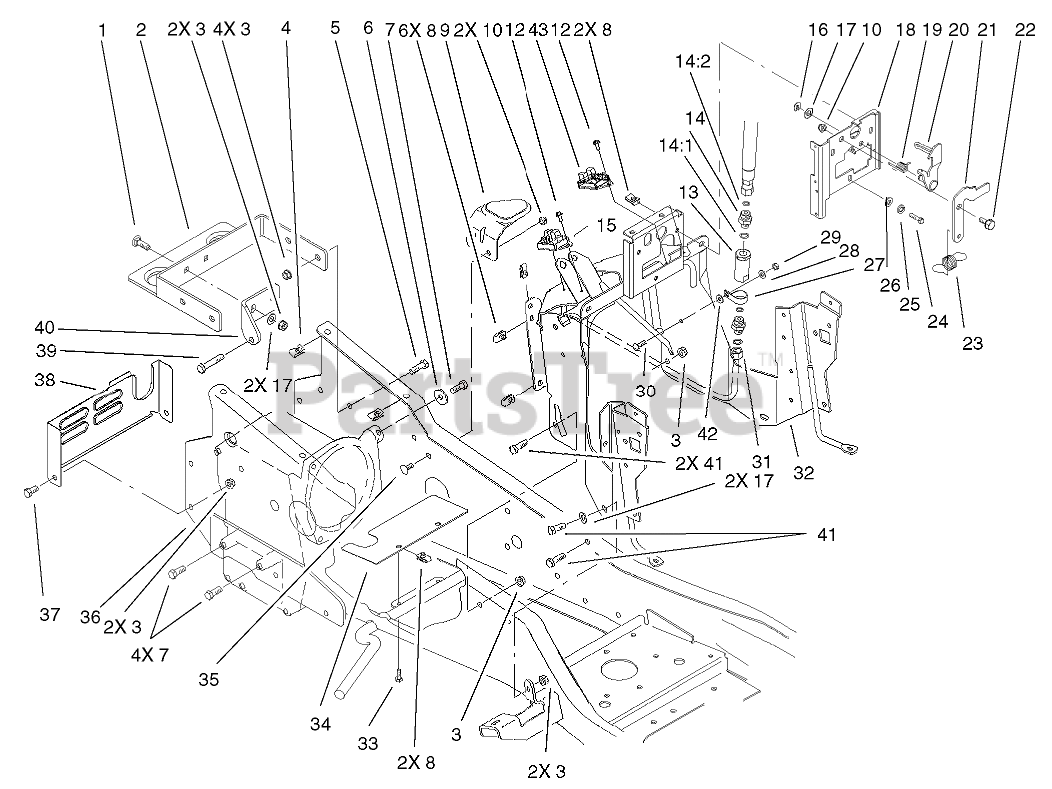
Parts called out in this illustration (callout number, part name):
1	BOLT-CARR
2	Support-Gas Tank
3	NUT-LOCK, NI
4	NUT-U
5	SCREW-HH
6	WASHER
7	SCREW-HH, LOCK
9	SUPPORT-TANK, FUEL
10	NUT-LOCK, NI
12	SCREW
13	FILTER-SCREEN, HYD
14	FITTING-HYD. STRAIGHT
14:1	O-RING
14:2	O-RING
15	MODULE-CRUISE
16	RING-RETAINING
17	WASHER-FLAT
18	BRACKET-LATCH
19	SPRING-LEVER, LATCH
20	LEVER-LATCH
21	LATCH-LEVER, TENSION
22	BOLT-SHOULDER
23	SPRING-LEVER, LATCH
24	SCREW-HH
25	WASHER-LOCK
26	WASHER-FLAT
27	CLAMP-R
28	WASHER-FLAT
29	NUT-LOCK, NI
30	BOLT-CARR
31	TUBE-HYD
32	TOWER ASM
33	SCREW-HH
34	BAFFLE-FAN
35	SCREW-CARR
37	SCREW-HH
38	COVER-REAR
39	SCREW-HH W/LOCTITE
40	Strap-Torque
41	SCREW-HH
42	PUSHNUT-RETAINER, BOLT
43	MODULE-CLUTCH
